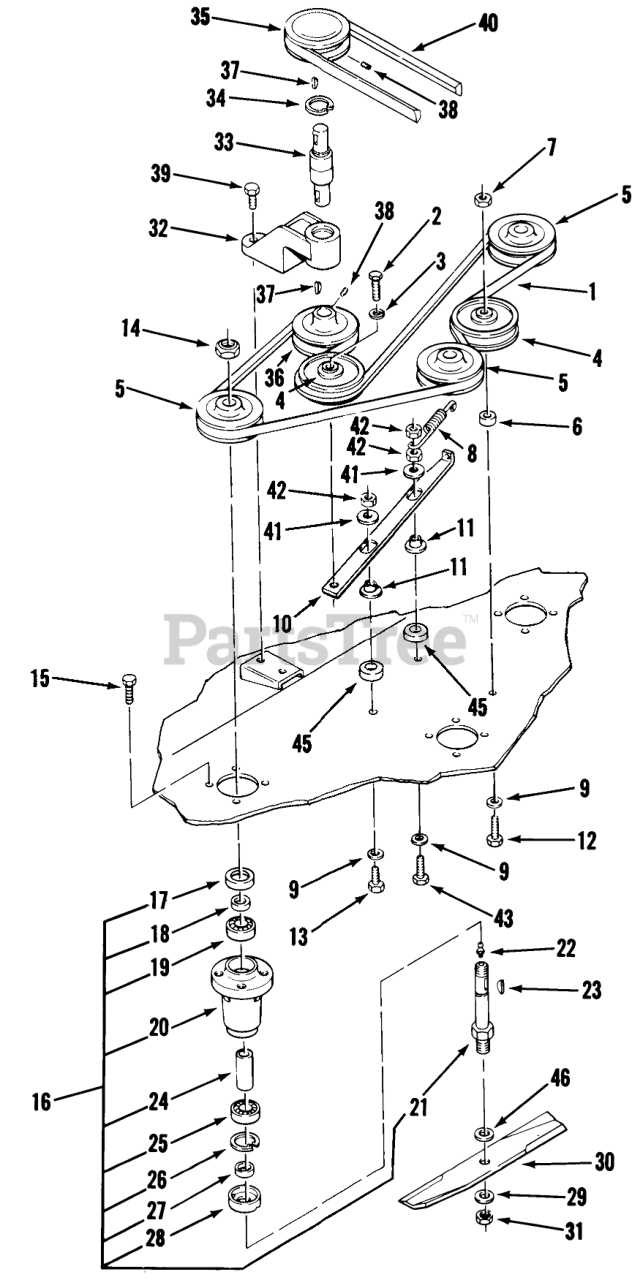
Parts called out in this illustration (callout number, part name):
1	V-BELT
2	Bolt
3	LOCKWASHER
4	Idler Pulley
5	PULLEY-BLADE DRIVE
6	SPACER
7	Nut
8	SPRING-EXTENSION
9	WASHER
10	BAR-SLIDER
11	SPACER-BUSHING
12	Bolt
13	BOLT
14	Nut
15	Bolt
16	Spindle Assembly
18	SPACER-SEAL
19	BEARING-BALL
20	HOUSING-SPINDLE
21	7" X 3/4" SHAFT.JAK
22	Zerk
23	Hi-Pro Key 3/16 x 5/8
24	SPACER
25	BEARING-BALL
26	Ring-Snap
27	SPACER-BLADE
28	CUP-SPINDLE
29	SpeciaI Washer
30	14IN BLADE KIT
31	Nut
32	HOUSING DRIVE BRG R
33	BEARING-INT SHAFT
34	Snap Ring
35	PULLEY
36	PULLEY-SPLIT
37	KEY-WOODRUFF
38	Set Screw
39	Bolt
40	Drive Belt
41	WASHER
42	Nut
43	Bolt
45	SPACER
46	Washer
